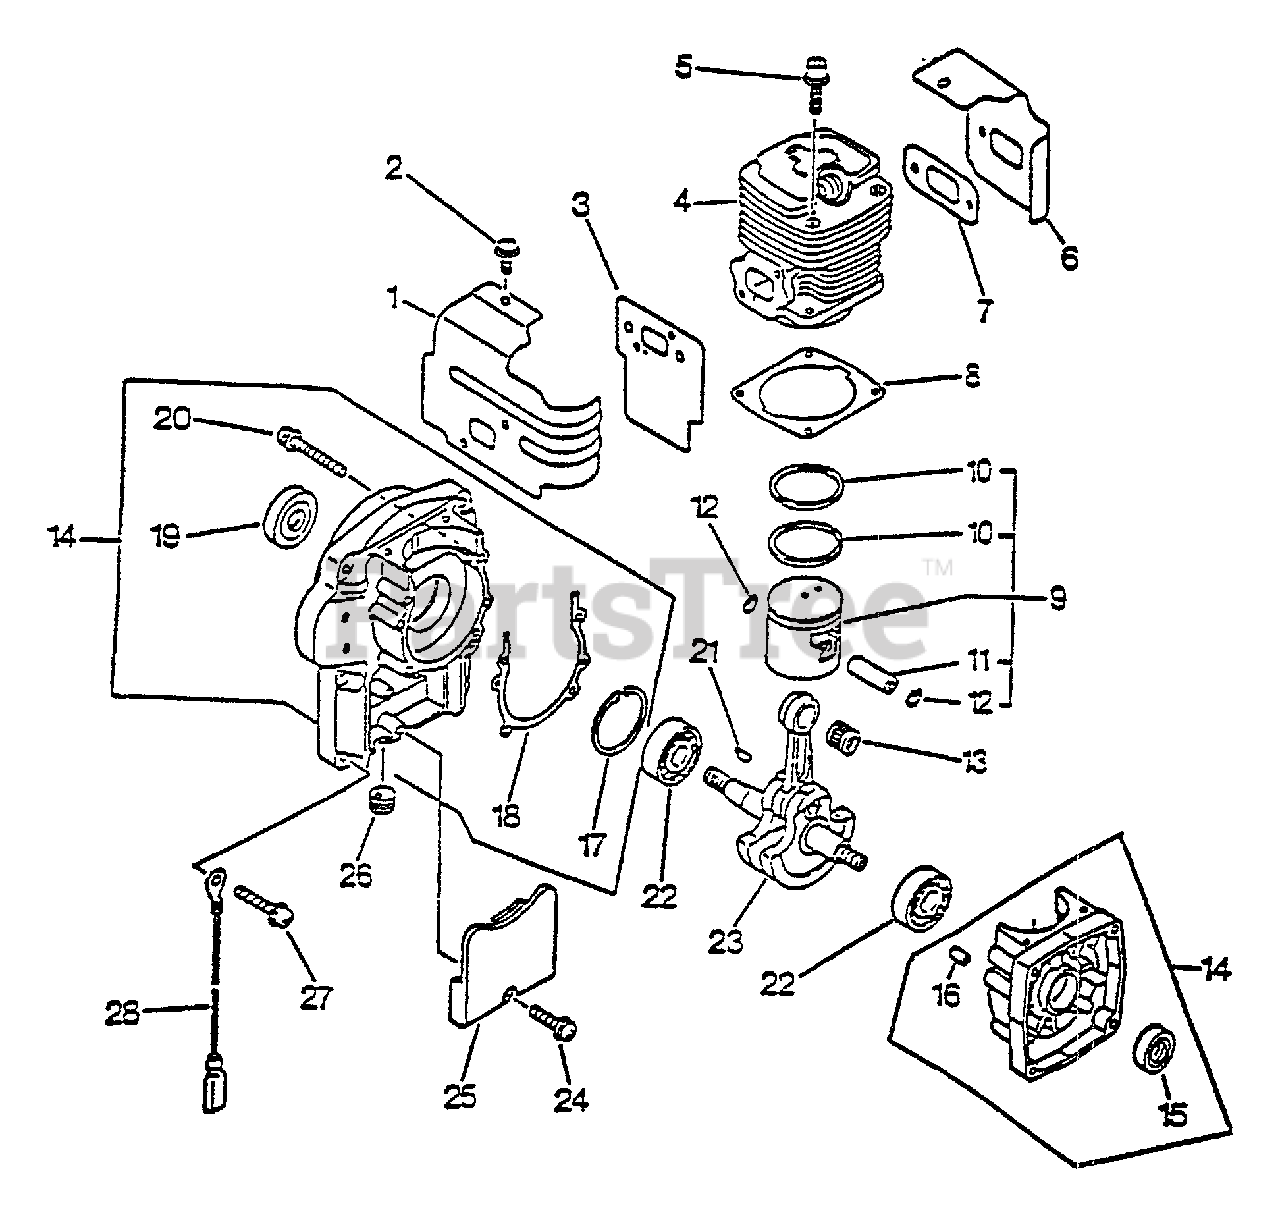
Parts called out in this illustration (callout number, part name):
1	COVER, CYLINDER
2	SCREW 5×10
3	GASKET, INTAKE
4	CYLINDER
5	BOLT 5×20
6	COVER, CYLINDER
7	GASKET, EXHAUST
8	GASKET, CYLINDER
9	PISTON KIT
10	RING, PISTON
11	PIN, PISTON
12	RING, SNAP 8
13	BEARING, NEEDLE
14	CRANKCASE KIT
15	SEAL, OIL
16	PIN, LOCATING 4
17	RING, SNAP 35
18	GASKET, CRANKCASE
19	SEAL, OIL 18
20	SCREW 5×40
21	KEY, WOODRUFF 3×14
22	BEARING, BALL 6202
23	CRANKSHAFT ASSY
24	SCREW 5×16
25	COVER, DUST
27	SCREW 5×32
28	LEAD - GROUND
